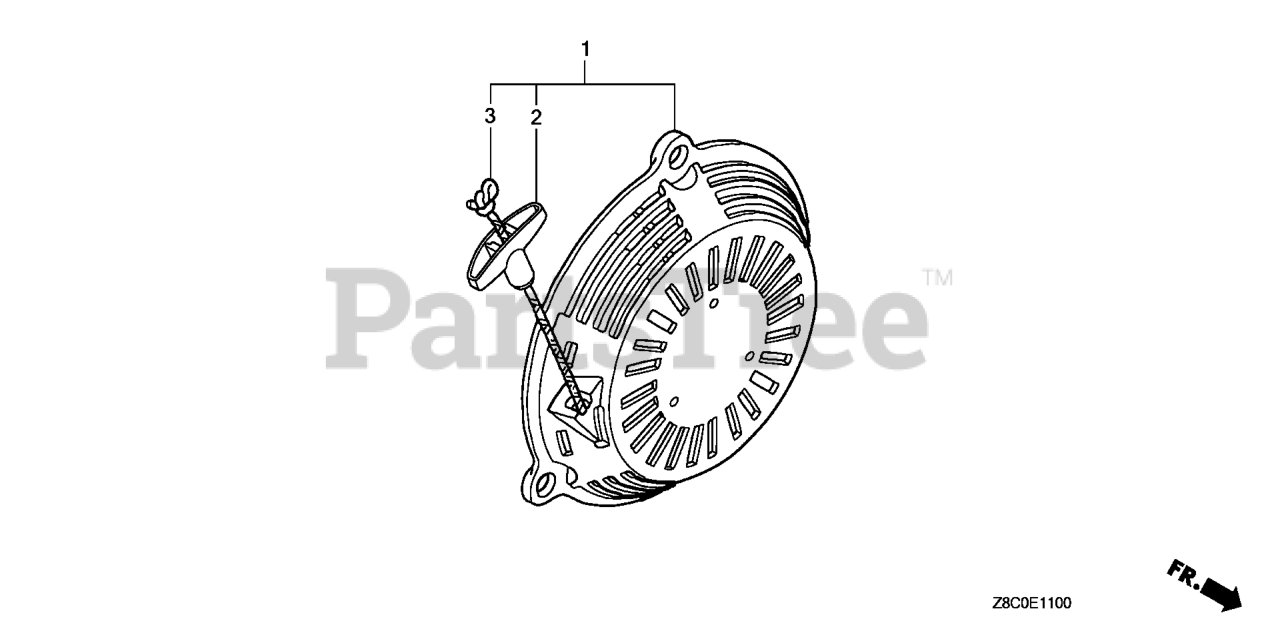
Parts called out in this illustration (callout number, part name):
1	STARTER ASSY., RECOIL *R280* (SHORT ROPE) (POWER RED)
1	STARTER ASSY., RECOIL *NH1* (SHORT ROPE) (BLACK)
2	KNOB, RECOIL STARTER
3	ROPE, RECOIL STARTER (#3.5X52")
